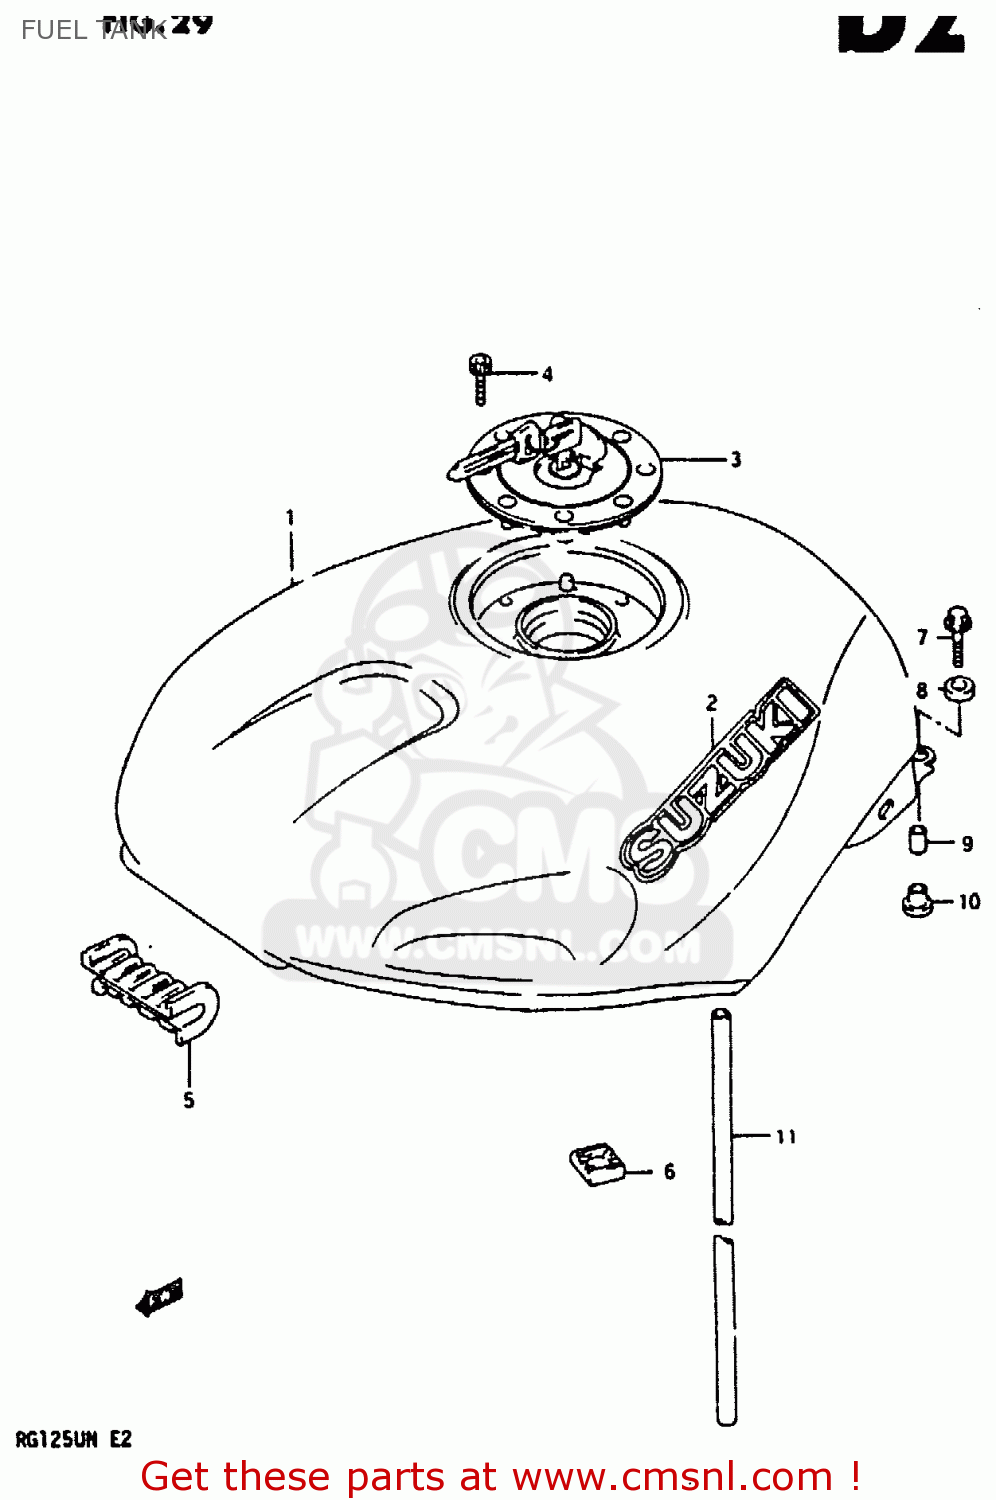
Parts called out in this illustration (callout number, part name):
1	TANK ASSY, FUEL (RED)
2	EMBLEM
3	CAP SET,FUEL TANK
4	BOLT(5X20)
5	CUSHION,FUEL TANK,FRONT
6	CUSHION,FUEL TANK SIDE
7	BOLT
8	CUSHION
9	SPACER
10	CUSHION
11	HOSE (7X10.2X1000)
